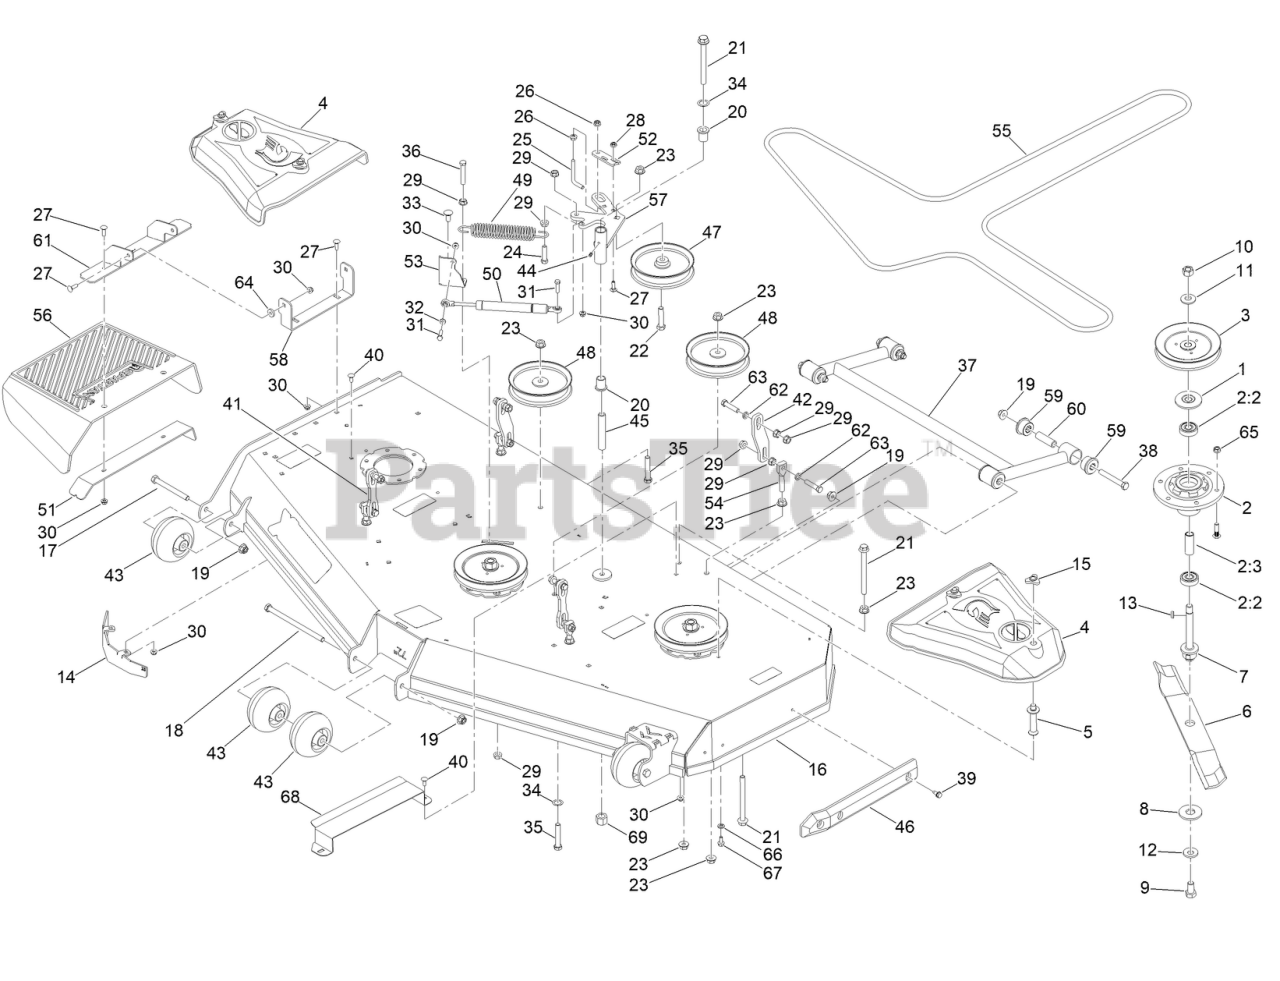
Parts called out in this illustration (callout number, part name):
1	GUARD,BEARING TOP .989
2	SPINDLE ASM 6" DECK
2:2	BEARING-BALL
2:3	SPACER, BEARING
3	PULLEY
4	COVER-BELT
5	PIN-BELT COVER
6	BLADE-ROTARY
7	SHAFT - SPINDLE
8	WASHER-HEX
9	M16X1.5-30MM C10.9 HEX BOLT
10	M20X1.5 C8.8 HEX NUT
11	M20 SPRING WASHER (44.5MMOD/ 3.3MM THK)
12	M16 SPRING WASHER (39MMOD/ 3.9MM THK)
13	6MM X 6MM X 20MM ROUNDED MACHINE KEY
14	BAFFLE-WIPER 72 PAINTED
15	NUT-KNOB
16	ASM-DECK W/DECALS
17	SCREW-HH
18	1/2-13 X 8-1/2 HEX C/S GR 2 ZINC YELLOW
19	NUT-LOCK
20	3/4IN ID X15/16IN OD X 1-1/8IN FLNG BUSH
21	1/2-13 X 5-1/2 HEX FLANGE BOLT GR 8 ZY
22	SCREW-HH
23	NUT-HHF
24	SCREW-HH
25	BOLT-L
26	3/8-16 HEX FLANGE NUT W/SERR ZINC YELLOW
27	5/16-18 X 1 CARRIAGE BOLT GR 8 YZ
29	NUT-HF
30	NUT-HF, NI
31	SCREW-HH
32	.312IDX.625ODX.062 THK THRUST BRG OI BRZ
33	SCREW-CARR
34	.767IDX1.125ODX.016 THK TRIP WV WASHER
35	1/2-13 X 2-3/4 HEX FLANGE BOLT (GR.8) YZ
37	72IN DECK FRAME STABILIZER ASSY PAINTED
38	1/2-13 X 3-3/4 HEX C/S (GR.5) ZC/YEL
39	SCREW-HWH, THREAD CUT
40	BOLT-CARR
41	MWR DECK SUSP LINK ASSY
42	72 RR HEIGHT ARM CONNECTING LINK PAINT
43	MWR ANTI-SCALP WHL W/O GREASE FITTING
44	1/4IN DRIVE TYPE GREASE FITTING YZ
45	MWR INNER IDLER SPACER
46	MWR NYLON DECK GUARD
47	6-3/4IN IDLER PULLEY 7/16IN SPACER ASM
48	6-3/4IN IDLER PULLEY 15/16IN SPACER ASSY
49	MWR DECK SPRING
50	IDLER GAS SPRING
51	2020 DECK CHUTE HINGE BACKER BRKT PAINT
52	DECK IDLER PULLEY BELT RETNR BRKT PAINT
53	DECK BELT IDLER DAMPER MTG BRKT PAINTED
54	MWR DECK HEIGHT ADJUSTMENT STUD
55	72 DECK BELT
56	2020 RT/SRT RUBBER DISCHARGE CHUTE
57	MWR DECK IDLER PULLEY ARM ASSY PAINT
58	MWR CHUTE MTG BRKT PAINTED
59	RED A80 SUSP BUSHING
60	UTV A-ARM BUSHING SLEEVE
61	RT/SRT DECK CHUTE HINGE ASSY PAINT
62	.443 ID X .749 OD X .125 THK NYLON BLACK
63	SCREW-HH
64	.312 ID X .875OD X .1875 THK F/W NYL
66	WASHER-LOCK
67	SCREW-HHF
68	BRACKET-COVER 72
69	NUT-LOCK, NI
